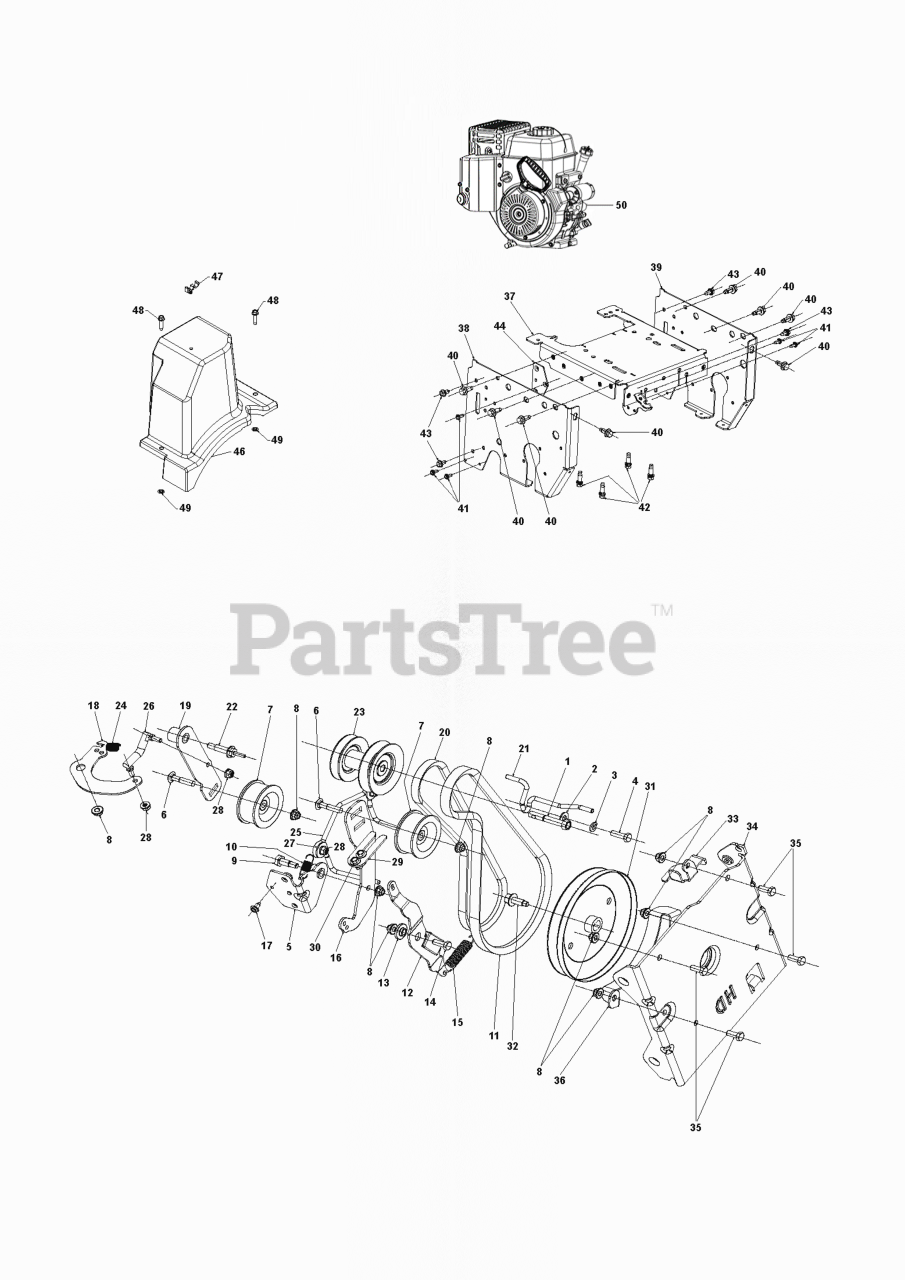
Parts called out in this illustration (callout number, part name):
1	BOLTS
2	WASHER 11/32 X 11/16 X 14 GA T
3	WASHER SPRING LOCK WASHER WITH
5	BRACKET WELDMENT, IDLER ARM ZI
6	BOLT 5/16-18 CARRIAGE 1.5L
8	NUT HEXAGON FLANGE 5/16-18 ST
9	SCREW HEX HEAD SHOULDER
10	SPRING IDLER RETURN
11	BELT 5L 39.15L
12	ARM IMPELLER BRAKE
13	BUSHING.BRAKE.ARM
14	BOLT HEXAGON BOLT 5/16-18 X 7/
15	SPRING EXTENSION - BRAKE
16	ARM IDLER BLACK ZINC
18	Bell Cranks
19	ARM DRIVE IDLER BLACK ZINC PLA
20	BELT 4L DRIVE
21	Belt Keepers
21	GUIDE BELT - 4L HYDRO, 5L IMPE
22	GUIDE BELT, SHOULDER SCREW
23	PULLEY 5L HYDRO
23	PULLEY WELDMENT
24	SPRING EXTENSION - DRIVE
25	GUIDE BELT - HYDRO 2 WITH FAN
26	LINK ASSY DRIVE IDLER
28	NUT FLG, NYLOCK, 1/4-20 GR G C
30	HEX.WASHER.HEAD 1/4-20 X .65
31	PULLEY IMPELLER DD 5L HD
32	SCREW HEXAGON HEAD FLANGE 3/8-
34	BRACKET AUGER HOUSING INTERFAC
35	SCREW HEXAGON HEAD SCREW 5/16-
36	BRACKET.BELT.KEEPER.LOWER.BLAC
40	SCREW HEXAGON HEAD FLANGE 3/8-
41	SCREW 14-20 X 5/8
42	BOLT 3/8-16X1-1/8
43	BOLT.HEX.HD.WASHER.5/16-18X.75
44	BRACKET NUT BLACK ZINC PLATE
46	COVER BELT ASM HIGH CRANK
48	SCREW HEX WASH THDRL BLK 1_4-
49	PALNUT 1/4
50	ENGINE LCT 414CC 12.5HP E-GOV
50	ENGINE RATO 420CC (EFI)
